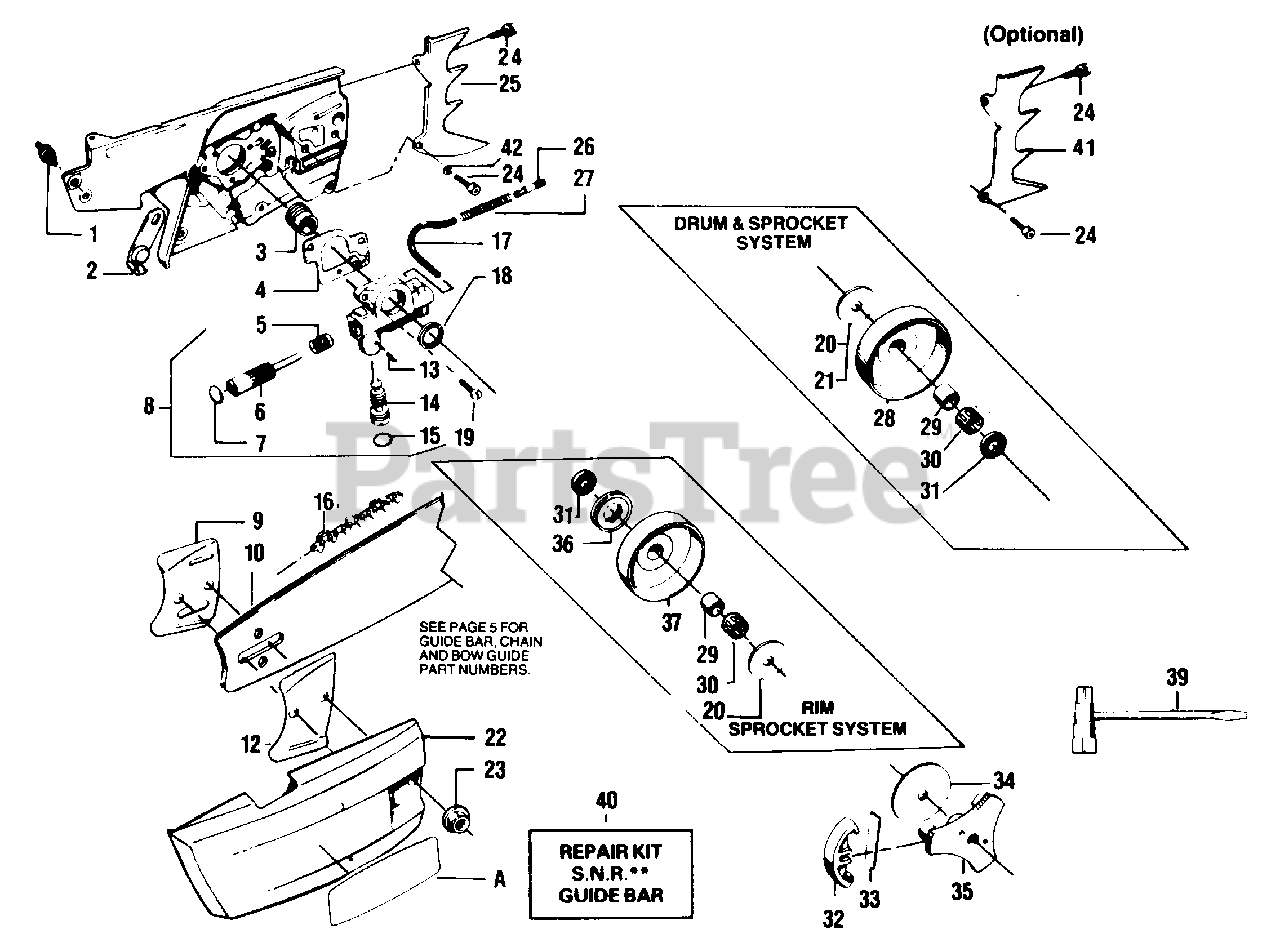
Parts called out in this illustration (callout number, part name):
1	Bumper - Bar Clamp
2	Bumper - Center Isolator Mount
3	Worm Gear
4	Gasket - Oil Pump Included in Engine - Gasket Kit 69180
5	Spring - Oil Pump Plunger
6	Plunger - Oil Pump
7	Plug - Oil Pump Body
8	Oil Pump Assembly (Incl. #5, 6, 7, 13, 14, 15, 17, 18 & 26)
9	Plate - Bar (Inner)
12	Plate - Bar (Outer)
13	Pin - Adj. Screw Stop
14	Screw - Oil Pump Adjusting
15	"O" Ring - Adj. Screw Included in Engine - Gasket Kit 69180
17	Line - Oil Pick-up (3-1/4" Long; Cut from No. 8132 Tubing)
18	Seal - Oil Pump Included in Engine - Gasket Kit 69180
19	Screw - 10 - 24 x 5/8
20	Washer - Sprocket Shroud - See Service Ref. 1
21	Moss Thrust Washer - Sprocket Shroud (Optional)
22	Bar Clamp
23	Nut - Bar Mounting (.375) (Includes Washer)
24	Screw - Spur - 1/4 - 20 x 5/8 - Socket Head
25	Spur - Heavy Duty
26	Weight & Filter - Oil Pick-up
27	Spring - Oil Line Protector
29	Inner Race - Clutch Drum
30	Bearing - Clutch
31	Washer - Thrust (Black) - See Service Ref. 1
32	Shoe - Clutch
33	Spring - Clutch Shoe (Green)
34	Washer - Clutch Shoe
35	Drive Plate - Clutch
37	Clutch Drum - Splined (for Rim Sprocket) - See Service Ref. 1
40	Repair Kit - Symmetrical S.N.R.** Guide Bars
41	Spur (Optional)
42	Lockwasher - Spur
A	Decal - Bar Clamp -
